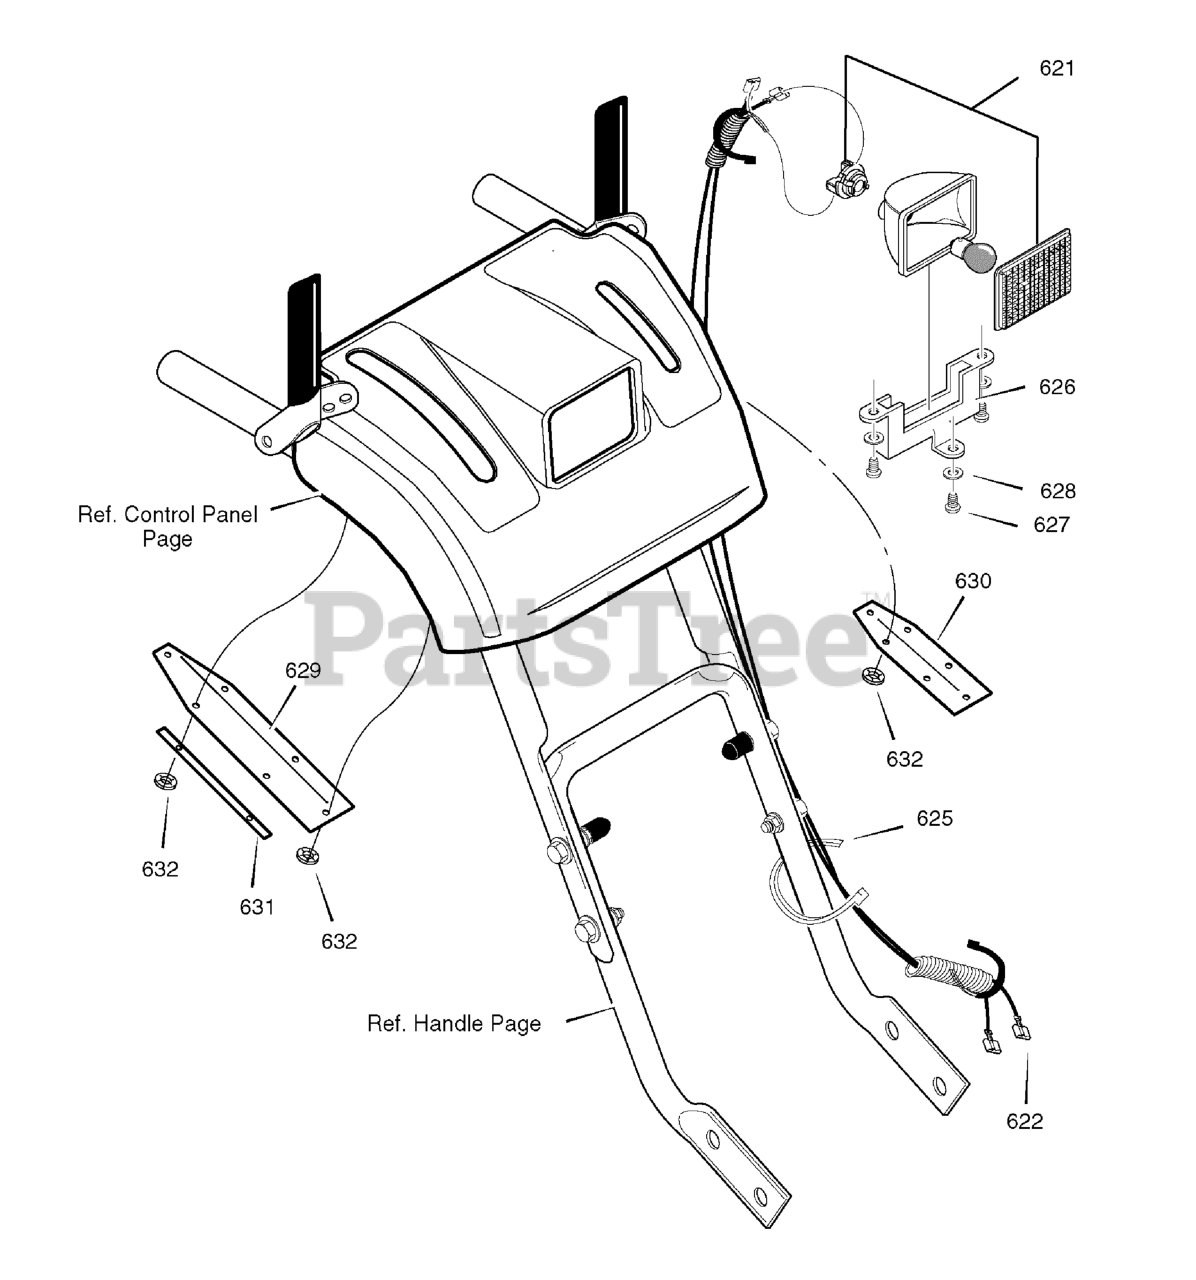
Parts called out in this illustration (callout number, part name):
621	LIGHT, HALOGEN
622	HARNESS, WIRE
625	TIE, CABLE
626	BRACKET, LIGHT
627	SCREW #8 X 0.50
628	WASHER, FLAT
632	NUT, PUSH
